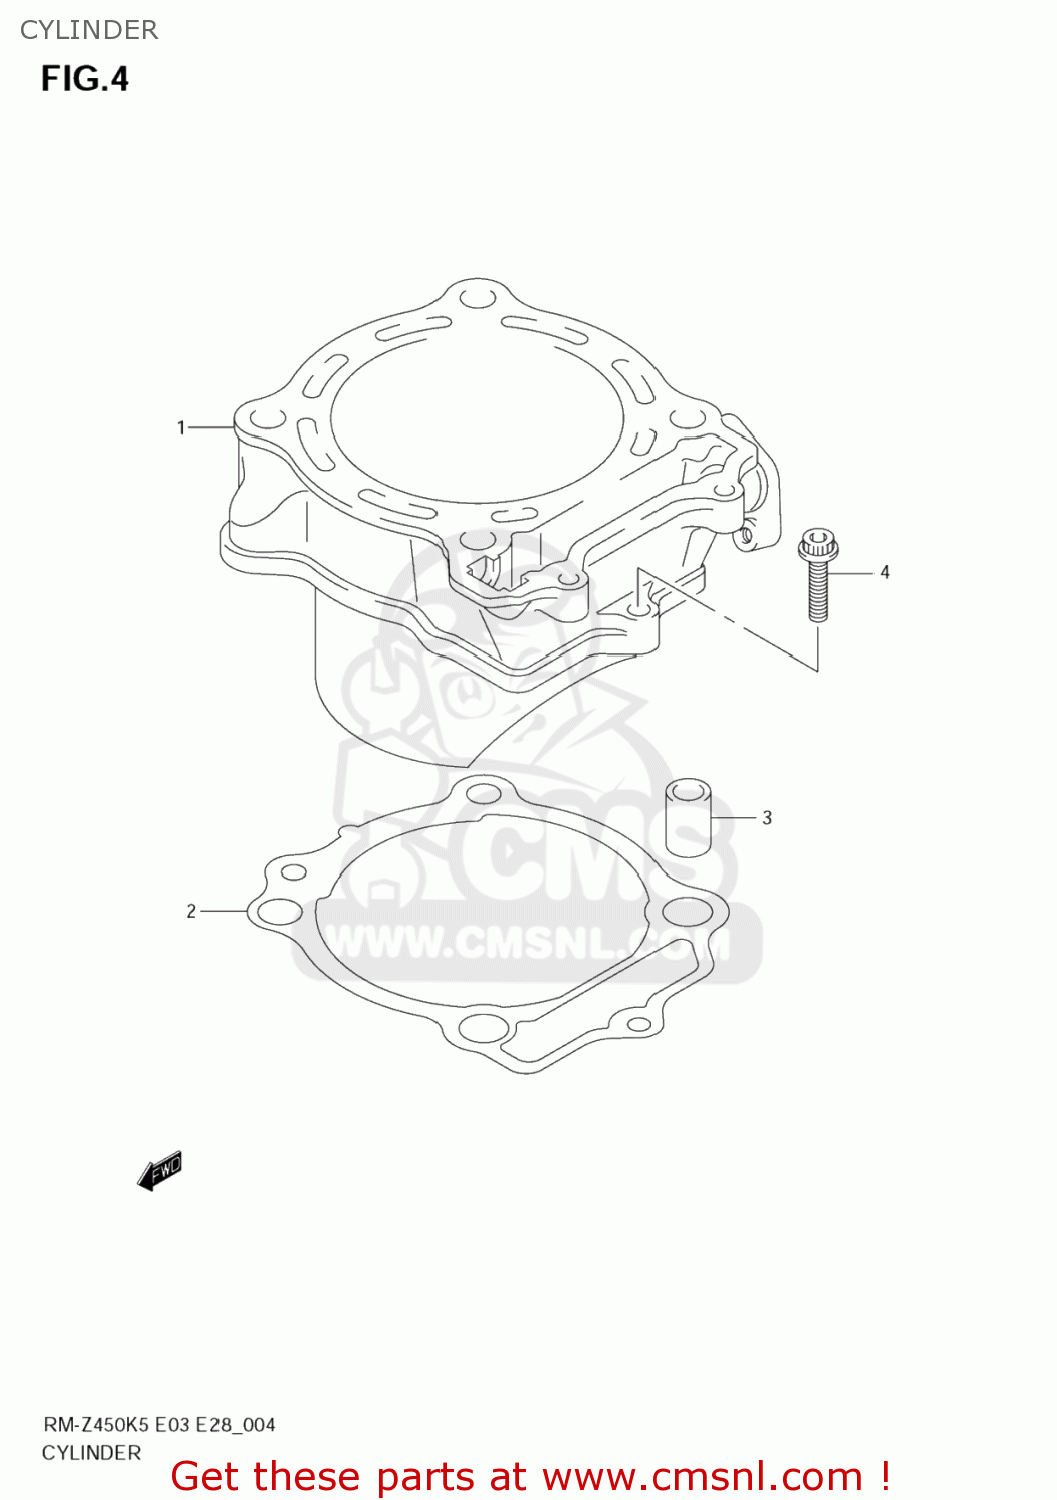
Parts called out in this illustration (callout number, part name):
1	CYLINDER
2	GASKET,CYLINDER (NAS)
3	PIN
4	BOLT
